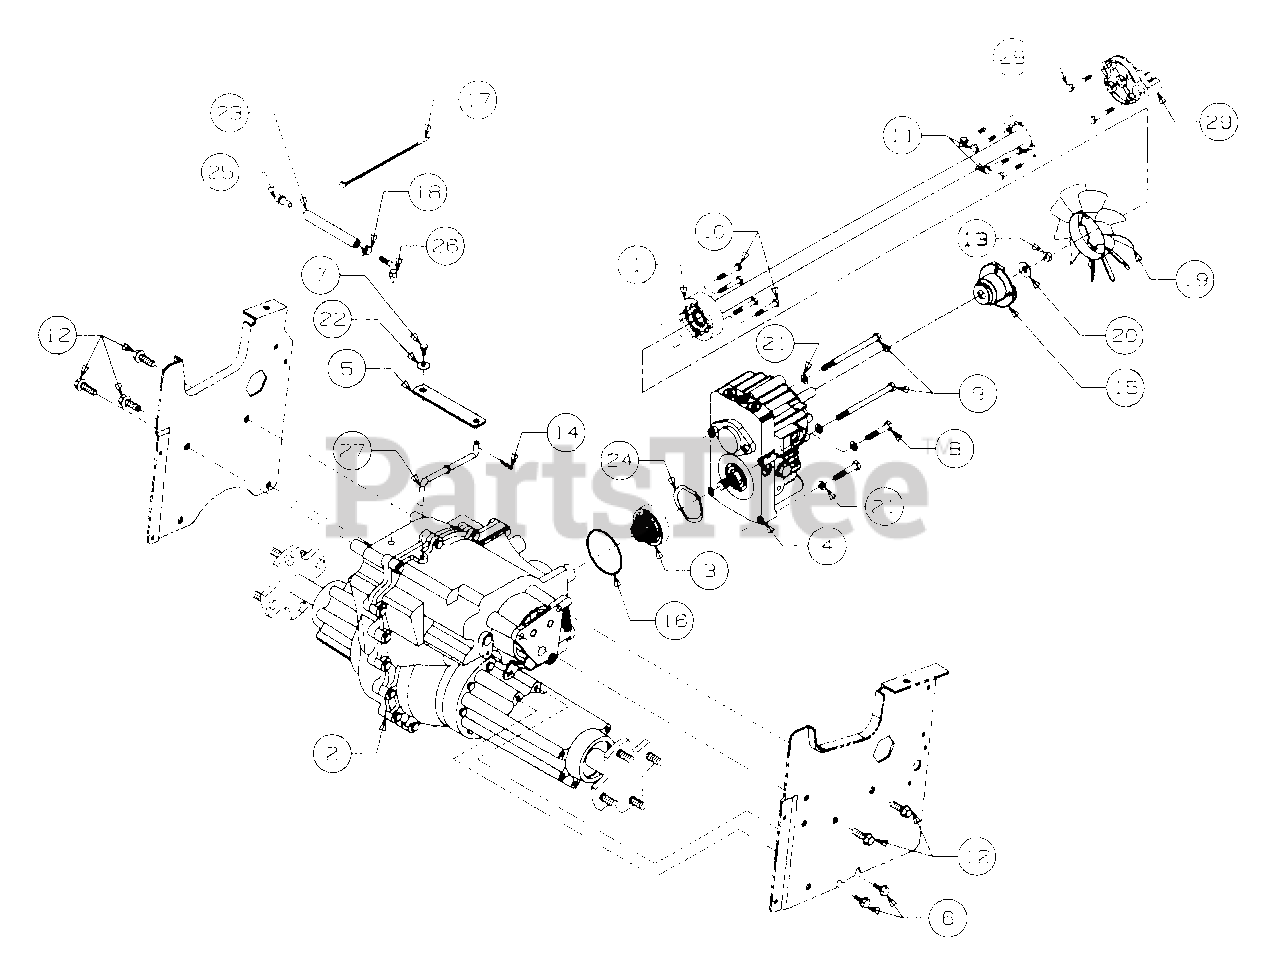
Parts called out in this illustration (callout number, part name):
1	Shaft Assembly, Drive, 27.87 Lg
2	Transmission Assembly, Hydro
3	Pinion Assembly, Input
4	Pump, Hydrostatic
5	Arm, Hydro Dump
6	Screw, Hex Wsh Tap, 5/16-18 x .75
7	Screw, Hex Wsh Tap, 1/4-20 x .75
8	Screw, Hex Cap, 5/16-18 x 1.75 GR5
9	Screw, Hex Cap, 5/16-18 x 4.5 GR5
10	Screw, Hex Patch, 1/4-20 x 1.25 GR5
11	Screw, Hex Patch, 1/4-20 x 1.62 GR5
12	Screw, Hex Wsh Tap, 3/8-16 x 1.25
13	Nut, Hex Center Lock Jam, 3/8-24
14	Pin, Internal Cotter, 5/16 Dia x 1.12
15	Adapter, Pump Tapered
16	O-Ring, 2.75 x .103
17	Tie, Self-Clinch Cable
18	Clamp, Hose
19	Fan, 10 Blade Cooling
20	Washer, Bell, .380 x .88 x .063
21	Washer, Lock, 5/16
22	Washer, Bell, .265 x .75 x .062
23	Line, Fuel, 7in
24	Washer, Wave, 1.96 x 2.44 x .06
26	Fitting, Elbow
27	Rod, Hydro Disengagement
28	Bolt
29	Engine/Driveshaft Coupler
